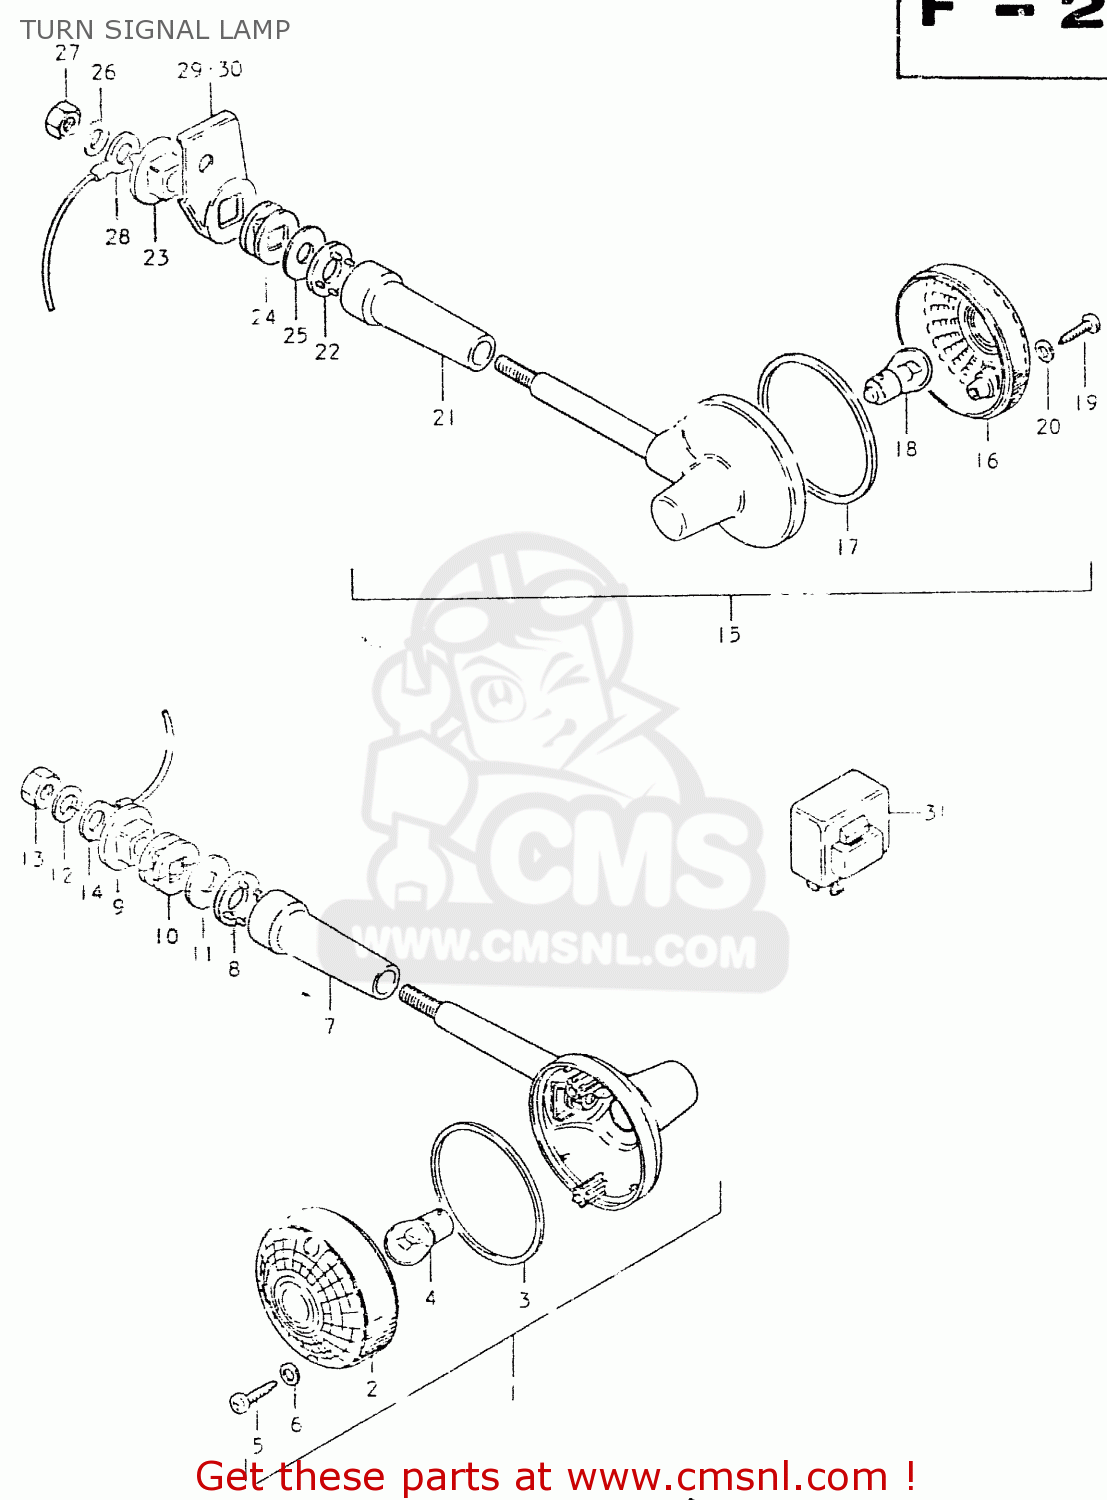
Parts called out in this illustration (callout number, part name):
1	LAMP, REAR TURN SIGNAL
2	LENS
3	GASKET (NAS)
4	BULB(12V23W,STANLEY,A4577A)
5	SCREW
6	GASKET (NAS)
7	COVER,STAY
8	SPACER
9	SPACER,TURN SIGNAL LAMP
10	CUSHION
11	WASHER (10.5X30X2.3)
12	LOCK WASHER
13	NUT
14	WIRE
15	LAMP, REAR TURN SIGNAL
16	LENS
17	GASKET (NAS)
18	BULB(12V23W,STANLEY,A4577A)
19	SCREW
20	GASKET (NAS)
21	COVER,STAY
22	SPACER
23	SPACER,TURN SIGNAL LAMP
24	CUSHION
25	WASHER (10.5X30X2.3)
26	LOCK WASHER
27	NUT
28	WIRE
29	BRACKET,RR TURNSIGNAL LAMP,R
30	BRACKET,RR TURNSIGNAL LAMP,L
31	RELAY,TURN SIGNAL
